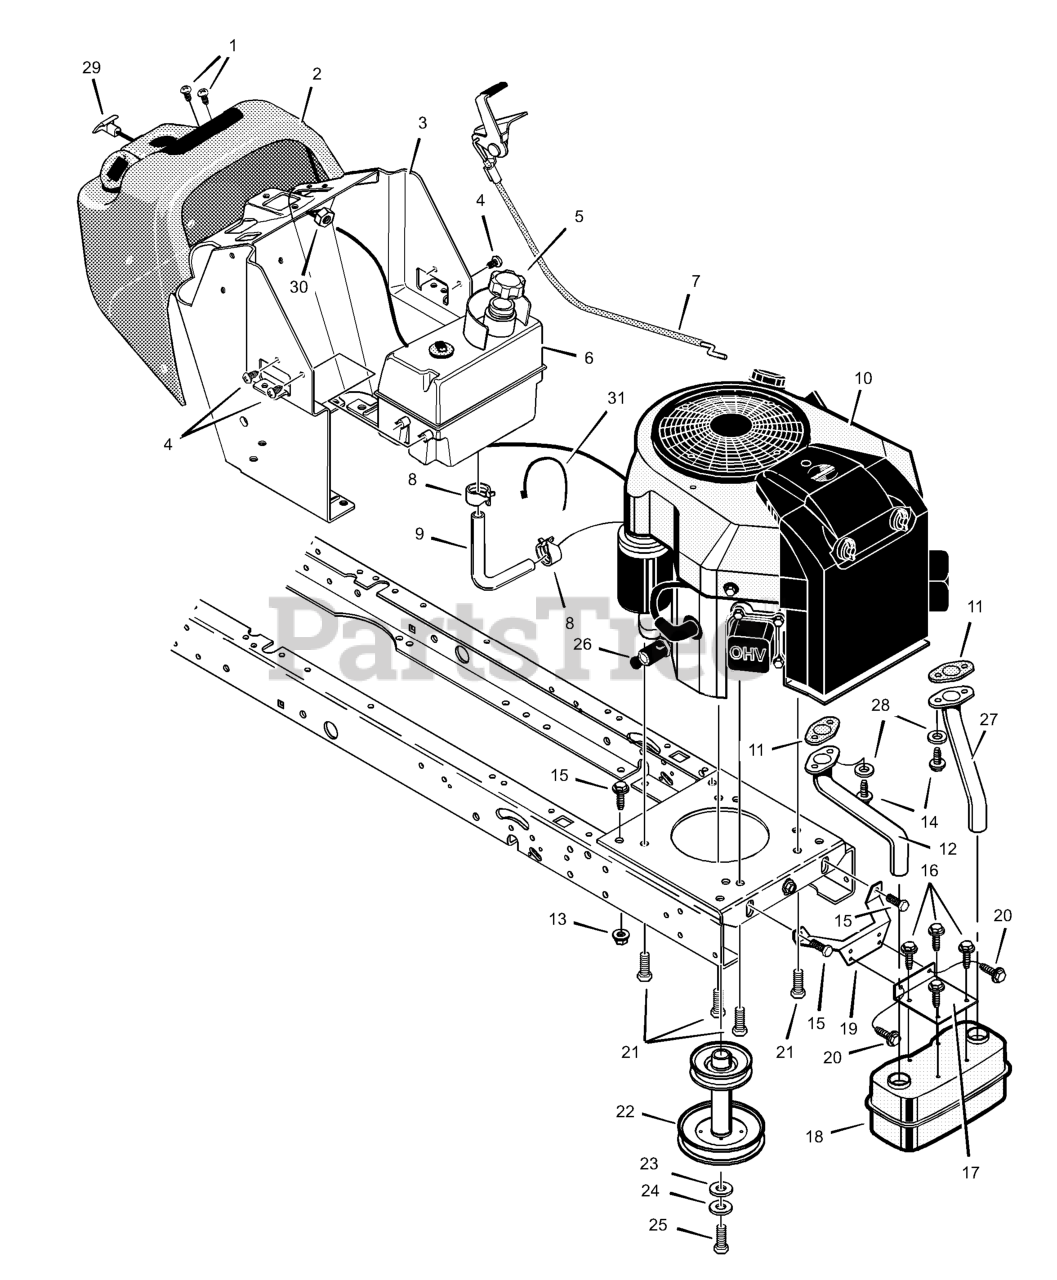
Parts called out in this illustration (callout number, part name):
1	Screw
3	Console
5	Cap, Fuel
6	Tank, Fuel
7	Control, Throttle
8	Clamp, Hose
9	Fuel Line (Must cut to length)
10	Engine *
11	Gasket, Exhaust
12	Tube, Right Exhaust
13	Nut
14	Bolt
17	Bracket, Muffler
18	Muffler
19	Bracket, Muffler Mount
21	Bolt, Engine Mount
22	Pulley, Stack
24	Washer, Star
25	Bolt, Hex
26	Drain, Oil
27	Tube, Left Exhaust
28	Washer
30	Nut
31	Strap, Tie
